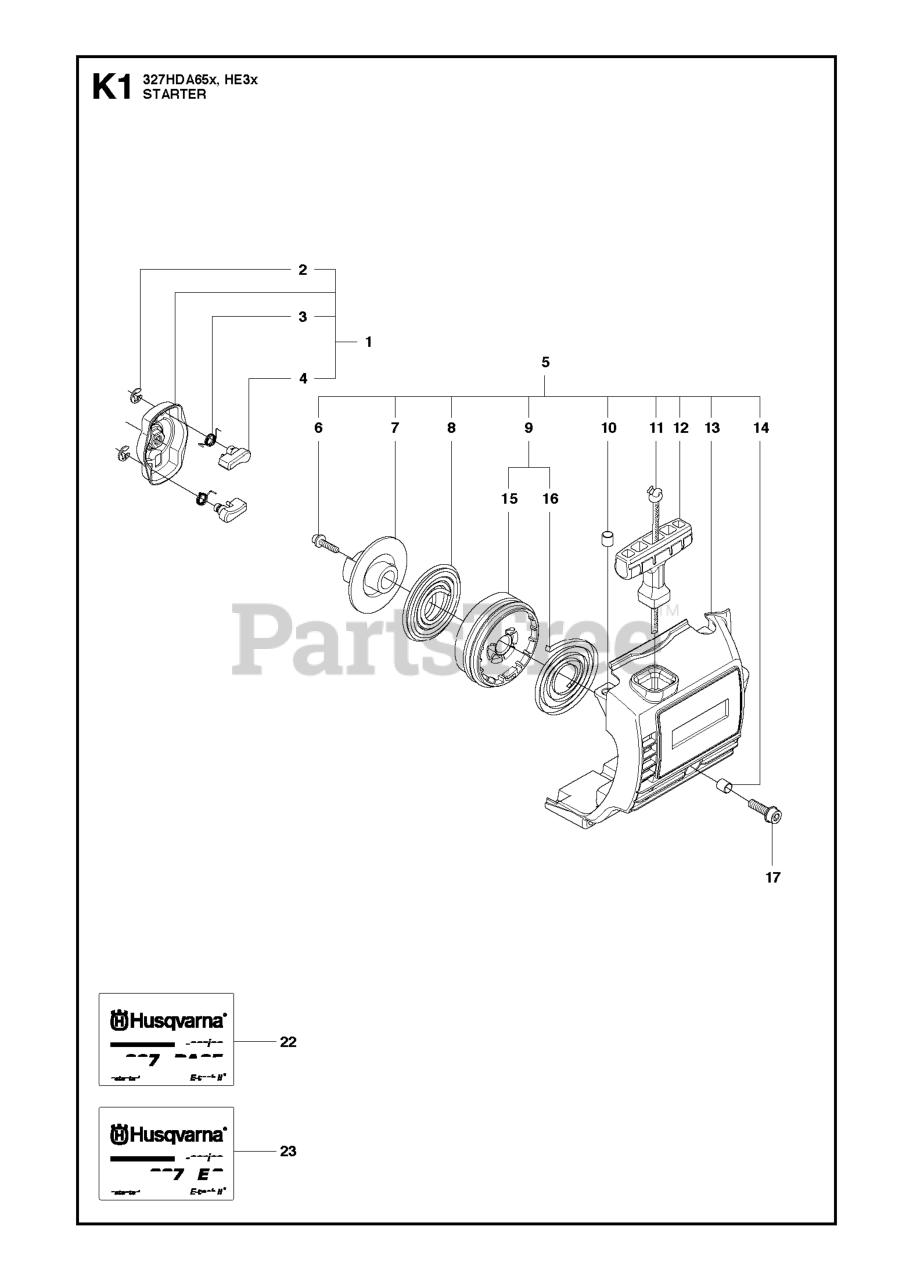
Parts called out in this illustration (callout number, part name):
1	STARTER PAWL BRIDGE
4	STARTER PAWL
5	RP STARTER ASSY
7	WHEEL
8	BALANCING SPRING
9	STARTER PULLEY
10	SPACING SLEEVE
11	STARTER ROPE
12	STARTER HANDLE
13	RP STARTER HOUSING
14	SPACING SLEEVE
15	STARTER PULLEY
17	SCREW IHSCFM
22	LABEL STARTER 327HDA65
23	LABEL STARTER 327HE3
